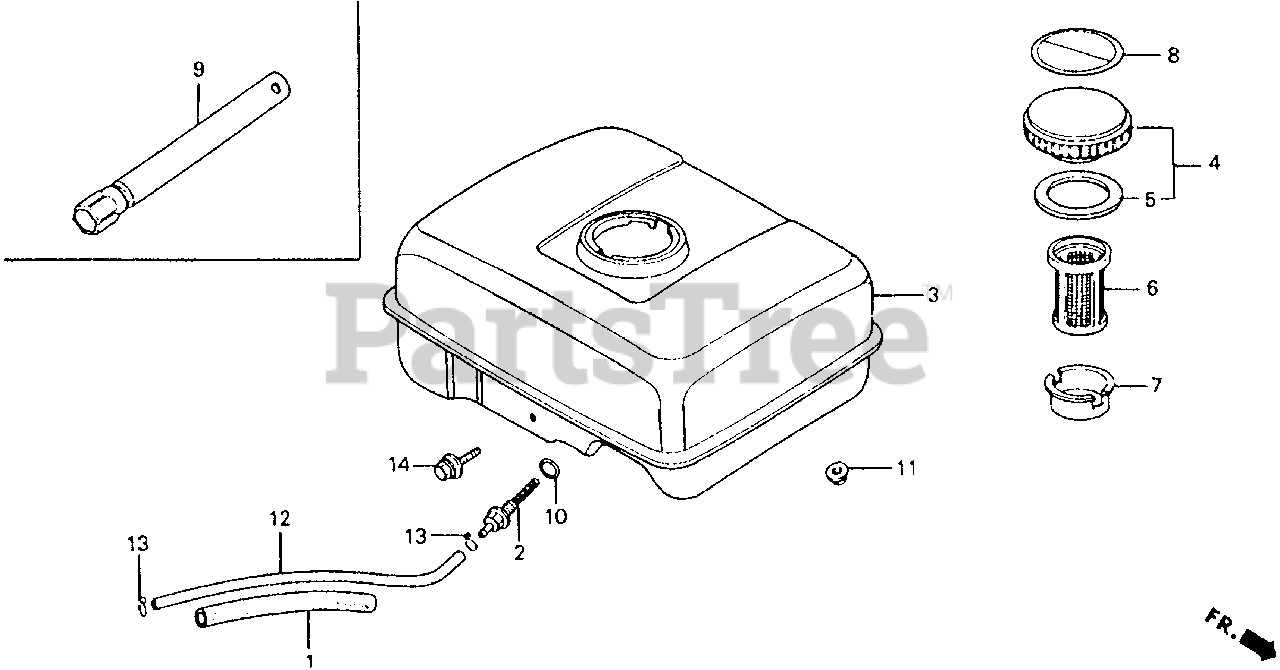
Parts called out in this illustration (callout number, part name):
1	RUBBER, SUPPORTER (107MM)
2	JOINT, FUEL TANK
3	TANK, FUEL *NH31* (MCKINLEY WHITE)
4	CAP, FUEL FILLER
5	GASKET, FUEL FILLER CAP
8	MARK, CAUTION (EXTERNAL)
10	O-RING (13.5X1.5) (ARAI)
11	NUT, FLANGE (6MM)
12	BULK HOSE, FUEL (4.5X3000) (4.5X140)
13	CLIP, TUBE (B8)
14	BOLT, FLANGE (6X25)
